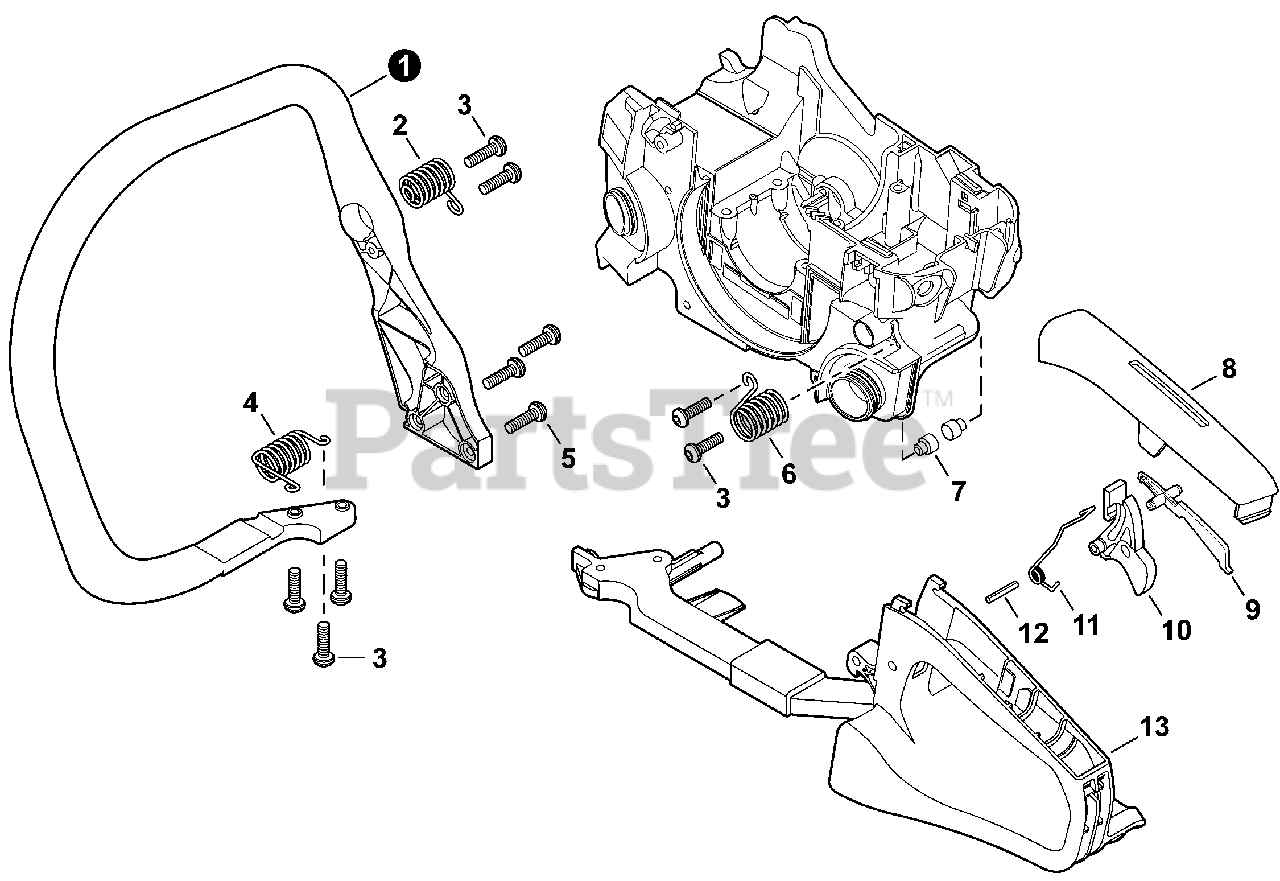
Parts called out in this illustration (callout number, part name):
1	HANDLE, FRONT
2	SPRING, COMPRESSION
3	BOLT, TORX 5×16
4	SPRING, COMPRESSION
5	BOLT, TORX 5×20
6	SPRING, COMPRESSION
7	CUSHION
8	COVER, HANDLE
9	LOCKOUT, THROTTLE
10	TRIGGER, THROTTLE
11	SPRING, TORSION
12	PIN, SPRING 4×25 SUS
13	HANDLE, REAR
